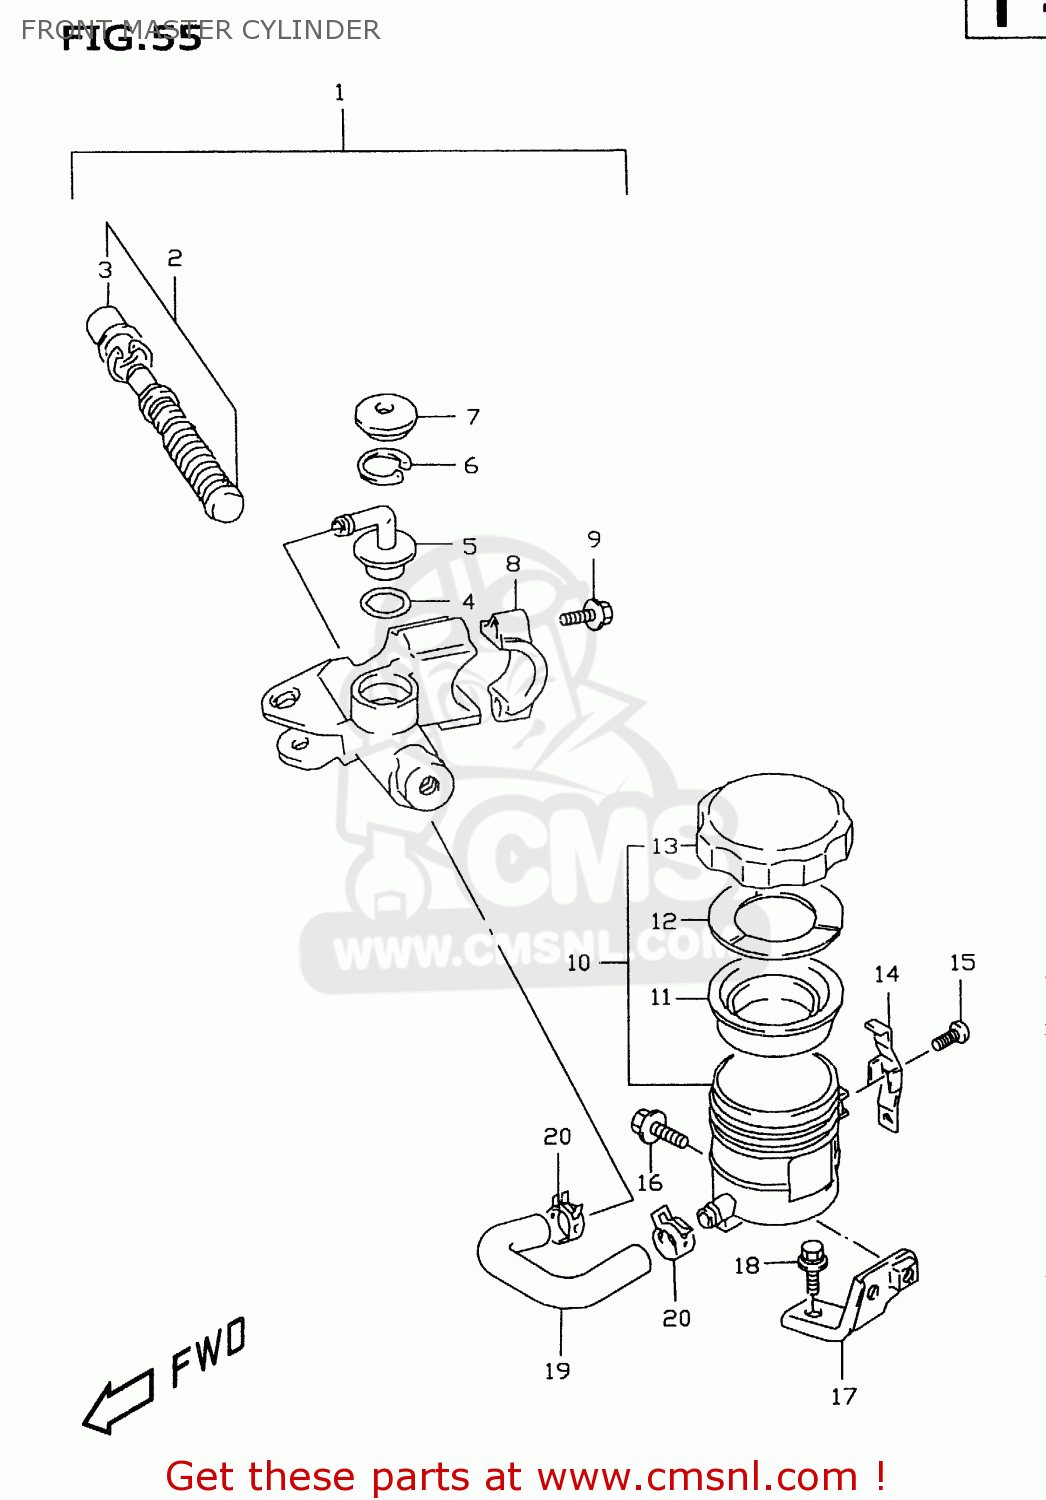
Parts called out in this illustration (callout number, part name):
1	CYLINDER ASSY,FR MASTER
2	PISTON & CUP SET
3	BOOT
4	O RING
5	CONNECTOR
6	CIRCLIP
7	COVER,DUST
8	HOLDER
9	BOLT(6X25)
10	TANK ASSY,RESERVOIR
11	DIAPHRAGM
12	PLATE,DIAPHRAGM
13	CAP
14	PLATE,RESERVOIR TANK CAP
15	SCREW
16	BOLT
17	BRACKET,RESERVOIR TANK
18	BOLT
19	HOSE,RESERVOIR TANK FR
20	CLAMP,RESERVOIR TANK FR
